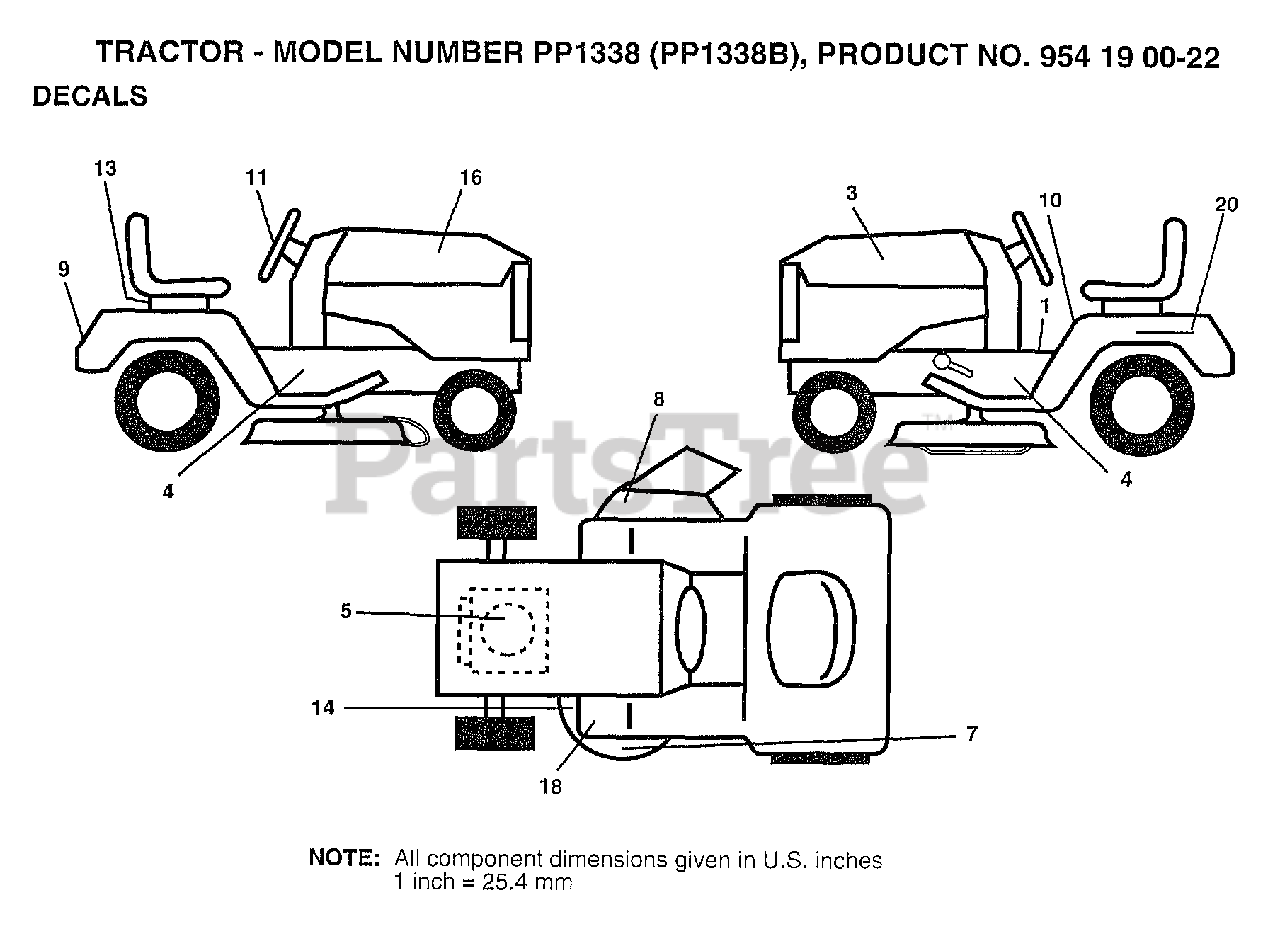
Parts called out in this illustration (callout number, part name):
1	"DECAL.OPER,SDL"
3	DECAL.HOOD.LH
4	DECAL CHASSIS
5	DECAL HP ENGINE
7	"DECAL,ENVIRO DECK"
8	"DECAL, WARNING"
9	DECAL.FENDER.BELT.GUARD
10	DECAL.CAUT.ENG/FR
11	DECAL INS STRG WH
13	RETAINER-SPRING
14	DECAL
16	DECAL.HOOD.RH
18	DECAL T
20	DECAL.BATRY.3-3908
